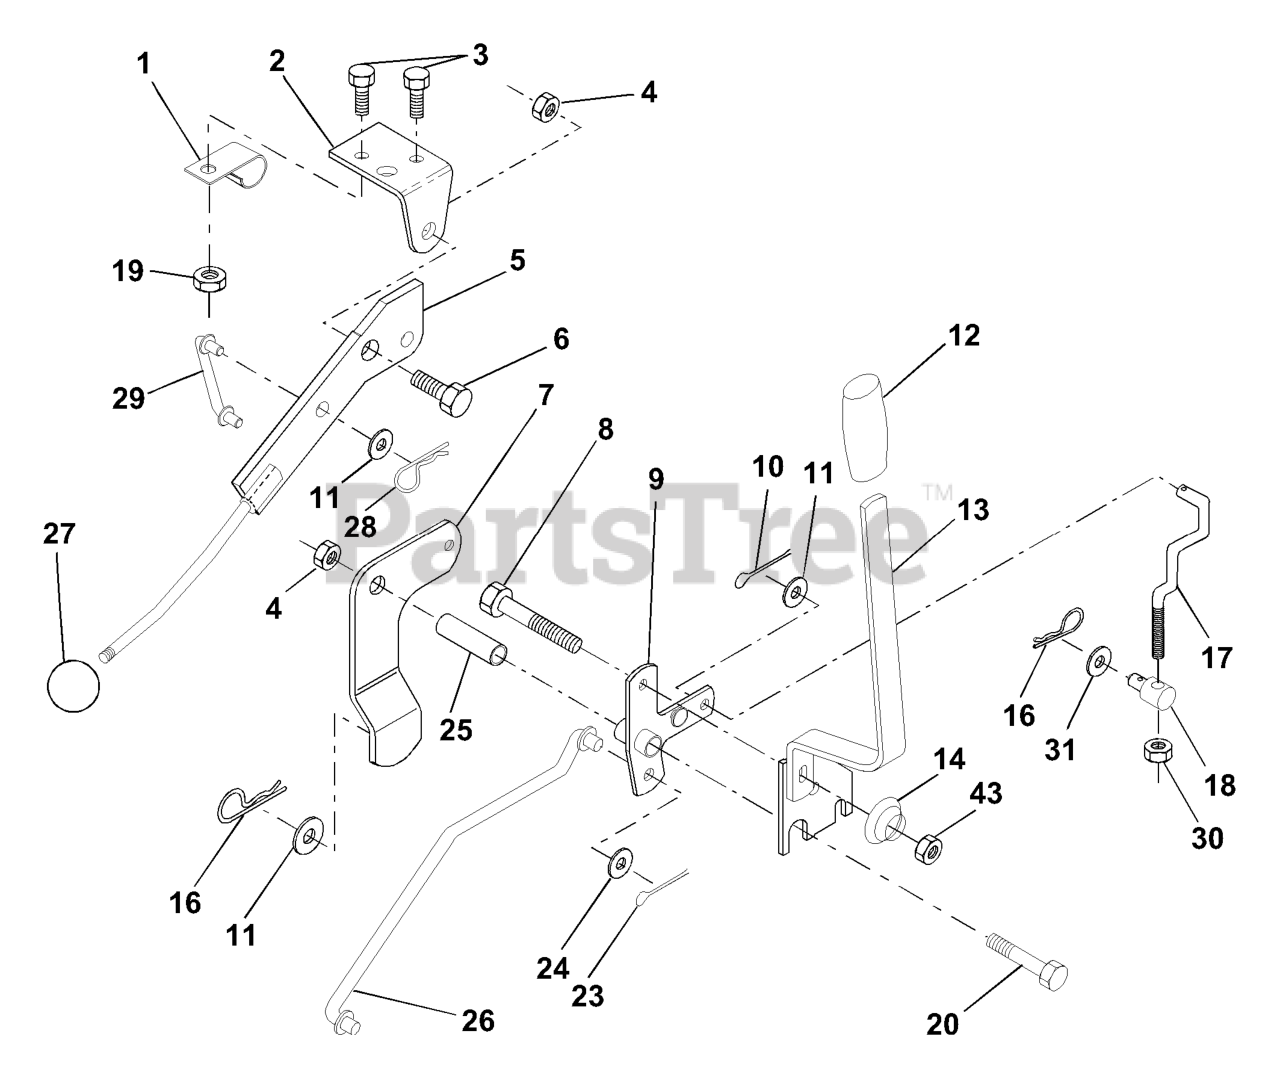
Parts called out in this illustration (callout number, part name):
1	CLIP,INSULATOR
2	BRKT CLUTCH
3	BOLT
5	CLUTCH LEVER
6	BOLT, SHOULDER LT
7	ASSEMBLY MOWER CLUTCH ARM
9	BELLCRANK,LIFT
10	COTTER PIN
11	WASHER
12	HANDLE GRIP
13	LIFT HANDLE ASSY
14	SPRING COMPRESSIO
16	SPRING TI
17	LINK LIFT FRT
18	TRUNNION.ADJUSTABLE.3/8-16
19	NUT.CROWNLOCK.1/4
23	PIN COTTER
24	WASHER GT
25	TUBE SPACER
27	KNOB T (3/8 HOLE)
28	RETAINER M
29	LINK MOWER CLUTCH
30	NUT
31	WASHER
43	NUT LOCK FLG 3/8-16 UNC
